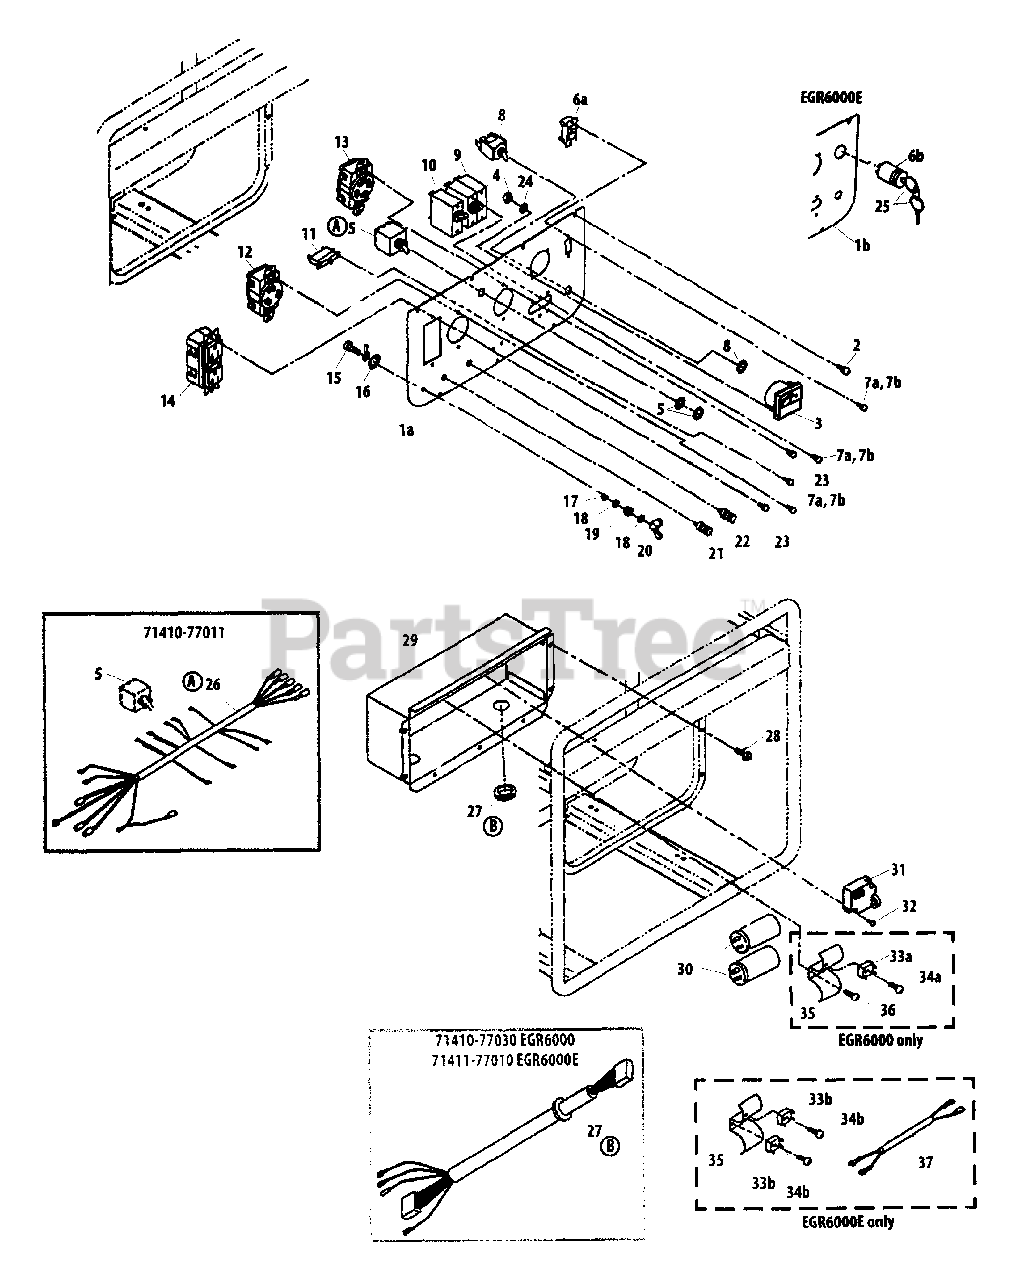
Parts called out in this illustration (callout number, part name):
1A	CONTROL PANEL
1B	CONTROL PANEL
5	TOGGLE SWITCH
6A	ROCKER SWITCH
6B	STARTER SWITCH
7A	SCREW
7B	SCREW
8	TOGGLE SWITCH
9	CIRCUIT PROTECTOR
10	CIRCUIT PROTECTOR
11	CIRCUIT PROTECTOR
12	OUTLET - 120V
13	OUTLET - 220V
14	OUTLET - 120V
16	TOOTH WASHER
18	LOCKWASHER
21	TERMINAL POST
22	TERMINAL POST
23	SCREW
24	LOCKWASHER
26	WIRING HARNESS
27	GROMMET
29	CONTROL BOX ASSY
30	CONDENSER
31	PRINT CIRCUIT
32	SCREW
33A	RECTIFIER
33B	RECTIFIER
34A	SCREW
34B	SCREW
35	CONDENSER HOLDER
37	WIRING HARNESS
71410-77011	WIRING HARNESS ASSY
71410-77030	WIRING HARNESS/ELECT.
71411-77010	WIRING HARNESS/RECOIL
